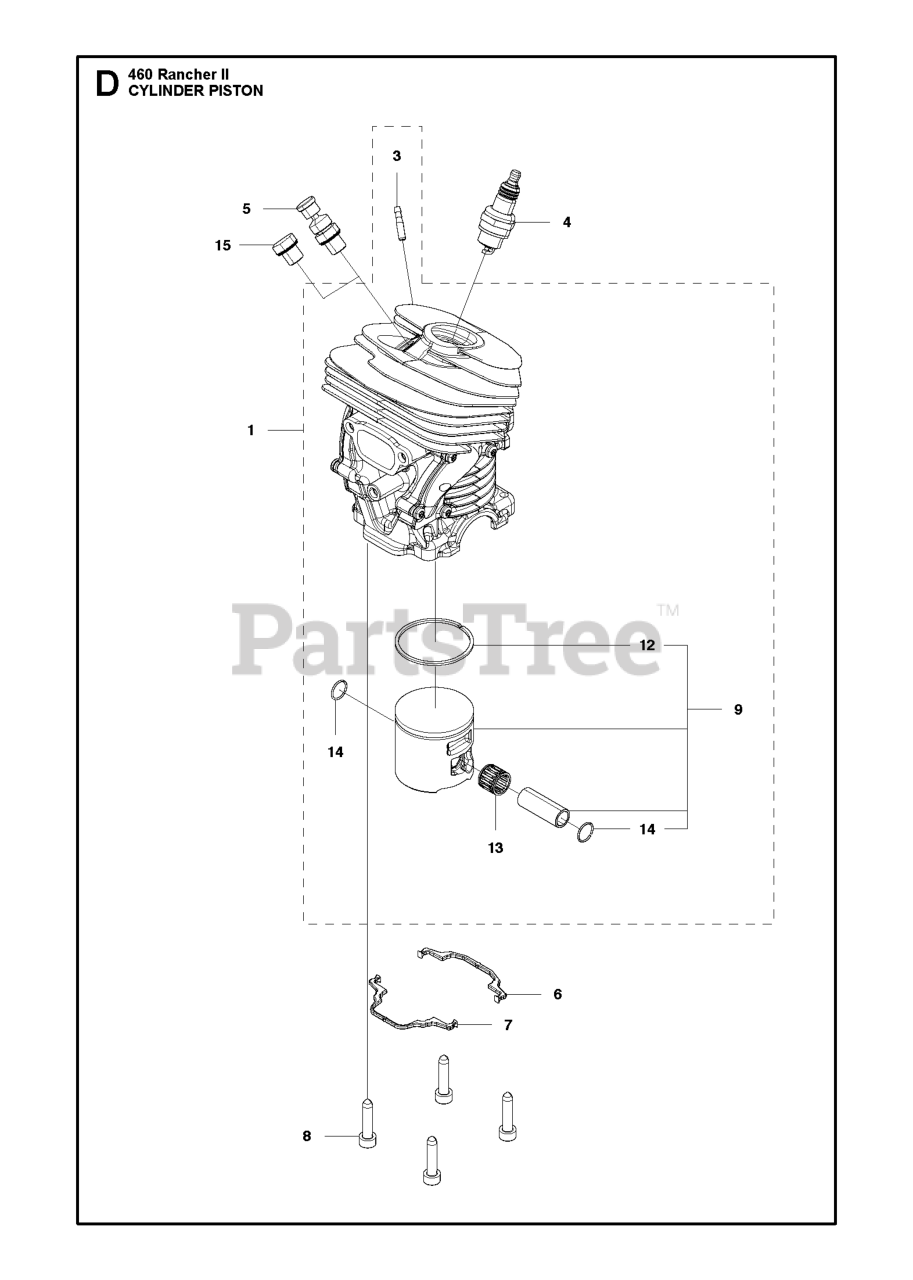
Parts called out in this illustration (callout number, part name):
4	SPARK PLUG M14X1.25 NGK BPMR7A
13	SUPPORT BUSHING
14	WRIST PIN CLIP
15	CYLINDER PLUG
